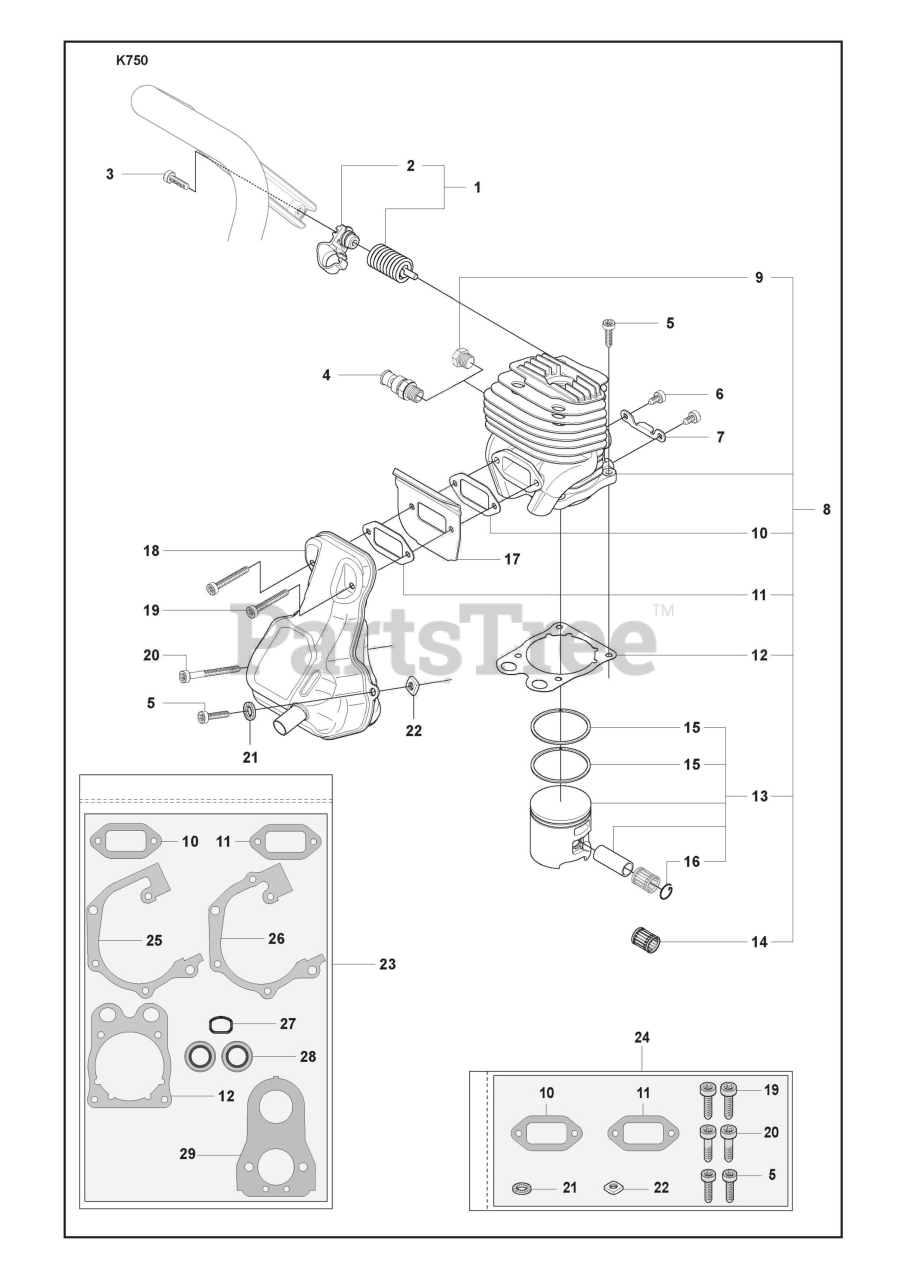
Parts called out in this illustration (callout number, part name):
1	VIB.INSULATOR
2	SPRING RETAINER
4	DECOMPRESSION VALVE
8	CYLINDER ASSY
11	GASKET MUFFLER
12	CYLINDER BASE GASKET
13	PISTON ASSY
14	NEEDLE BEARING
15	PISTON RING
17	COOLING PLATE
18	MUFFLER
22	NUT SQUARE
23	GASKET KIT
24	MUFFLER MOUNTING KIT
25	GASKET CRANKCASE
26	GASKET CRANKCASE
28	SEALING RING
29	GASKET CARBURETTOR
